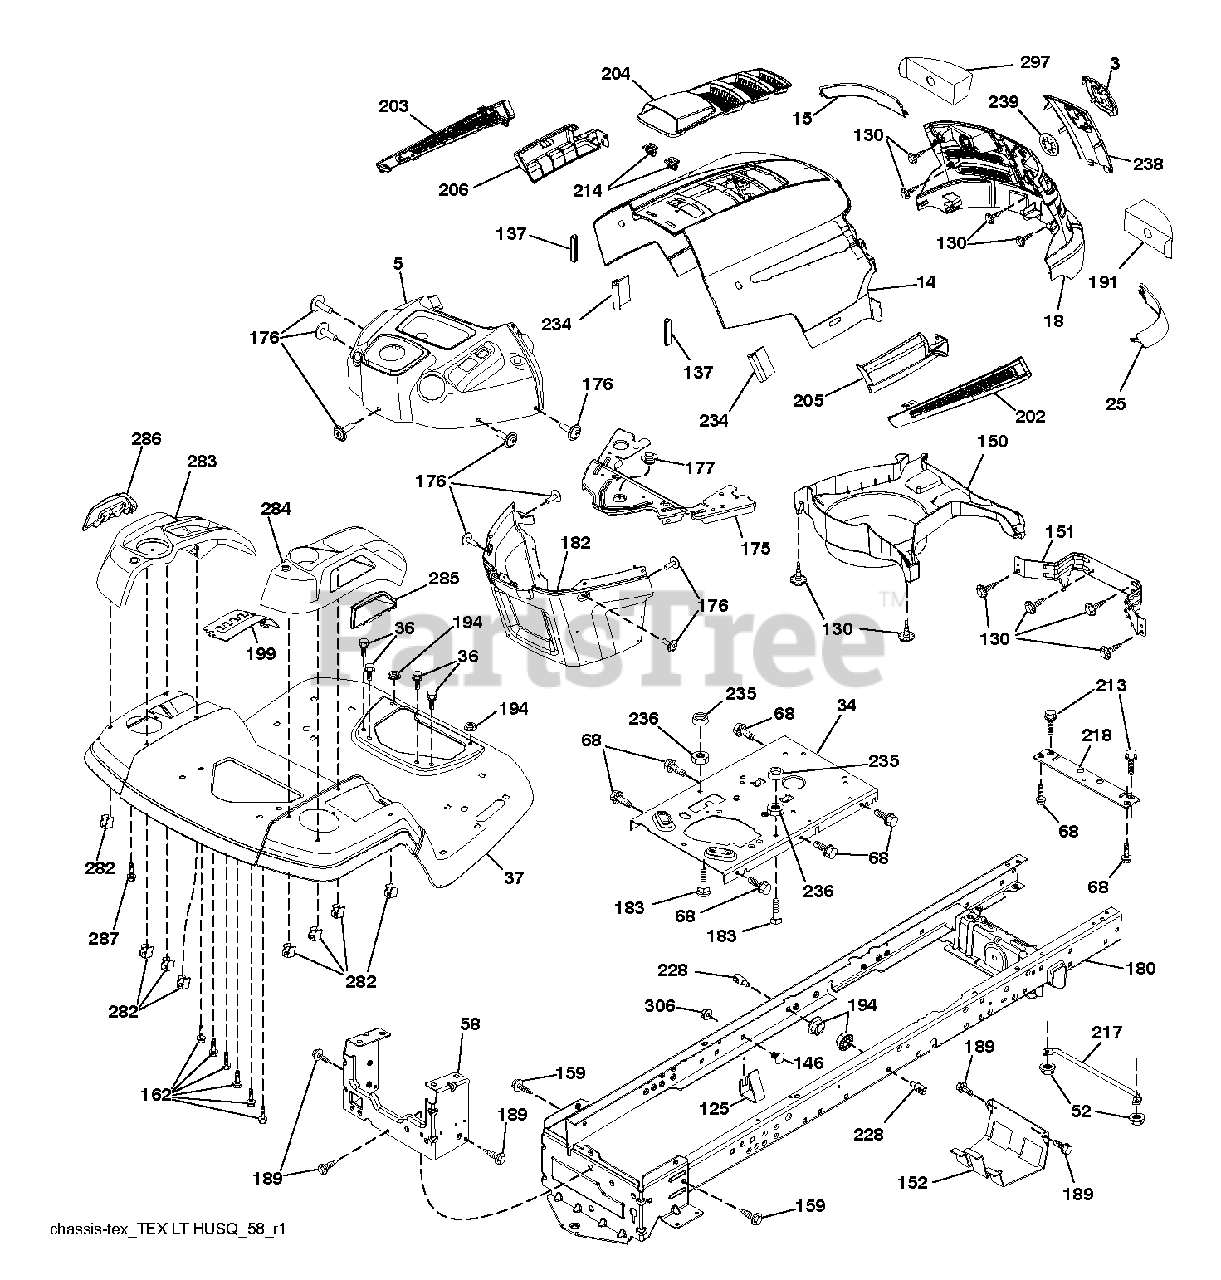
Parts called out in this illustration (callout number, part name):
3	LOGO.HUSQ.GT.LT.CROWN.H
5	SUBASM.DASH.UPPER.W/BUMPER
14	HOOD.HUSQVARNA.LT.ORANGE
15	LENS.HUSQVARNA LT.RH
18	GRILLE.SVC.HUSQVARNA.GREY
25	LENS.HUSQVARNA LT.RH
34	PLATE.ENGINE.WELDED.CHASSIS
36	SCREW 5/16"
37	FENDER.TLT.FS.W/CUPHLD.ORANGE
52	LOCKNUT
58	DRAWBAR UPPER 2PC SMALL FENDER
68	SCREW LT
125	CLIP.FUEL.LINE
130	SCREW.#10 X 0.750.BOS
137	BUMPER DASH
146	BOLT.RDHD.SHT.SQNK.3/8-16X5/8
151	BRACKET PIVOT
152	SHIELD.BROWNING.W/TEX
159	SCREW, 3/8-16X3/4
162	SCREW.HI-LO.CONSOLE
175	CROSSMEMBER
176	SCREW.#10-24X5/8.RN.QU
177	BUSHING STEERING
180	CHASS.WLDMNT.TL.12GA/2P.48/54
182	DASH.LOWER.PREDATOR LT
183	BOLT.5/16-18X1-1/4 FULL THD
189	SCREW
191	INSERT.REFLECTIVE.RH.
194	NUT LOCK HEX FLANGE 5/16-18
199	PLATE.DECK.LIFT.HUSQ.LT
202	VENT.SIDE.HUSQVARNA.LT.RT
203	VENT.SIDE.HUSQVARNA.LT.LFT
204	SUBASM.TOP.VENT.HUSQ.LT
205	SKIRT.SIDE.HUSQVARNA.LT.RT
206	SKIRT.SIDE.HUSQVARNA.LT.LEFT
213	BOLT
214	CLIP.RETAINER.TINNER.
217	ROD.PIVOT.HOOD
218	X-PIECE.HOOD.STOP.NON/
228	STUD.FASTNER.W/ANTI-ROTATE
234	BUMPER.HOOD.TEX.HUSQVARNA
235	SPACER FENDER
236	NUT.CENTERLOCK.5/16-
238	TRIM.HUSQ LT.668
282	CLIP.RETAINER.CONSOLE.LT.HUSQ
283	CONSOLE.ASM.LFT.RSF.HUSQ.LT
284	CONSOLE CONSOLE.HUSQ.SHIFT.HYD
285	CONSOLE INSERT RH
286	CONSOLE.INSRT.LH.HUSQ.LT.BLACK
287	SCREW 1/4X20
297	INSERT REFLECTIVE
306	NUT LOCK FLG 3/8-16 UNC
